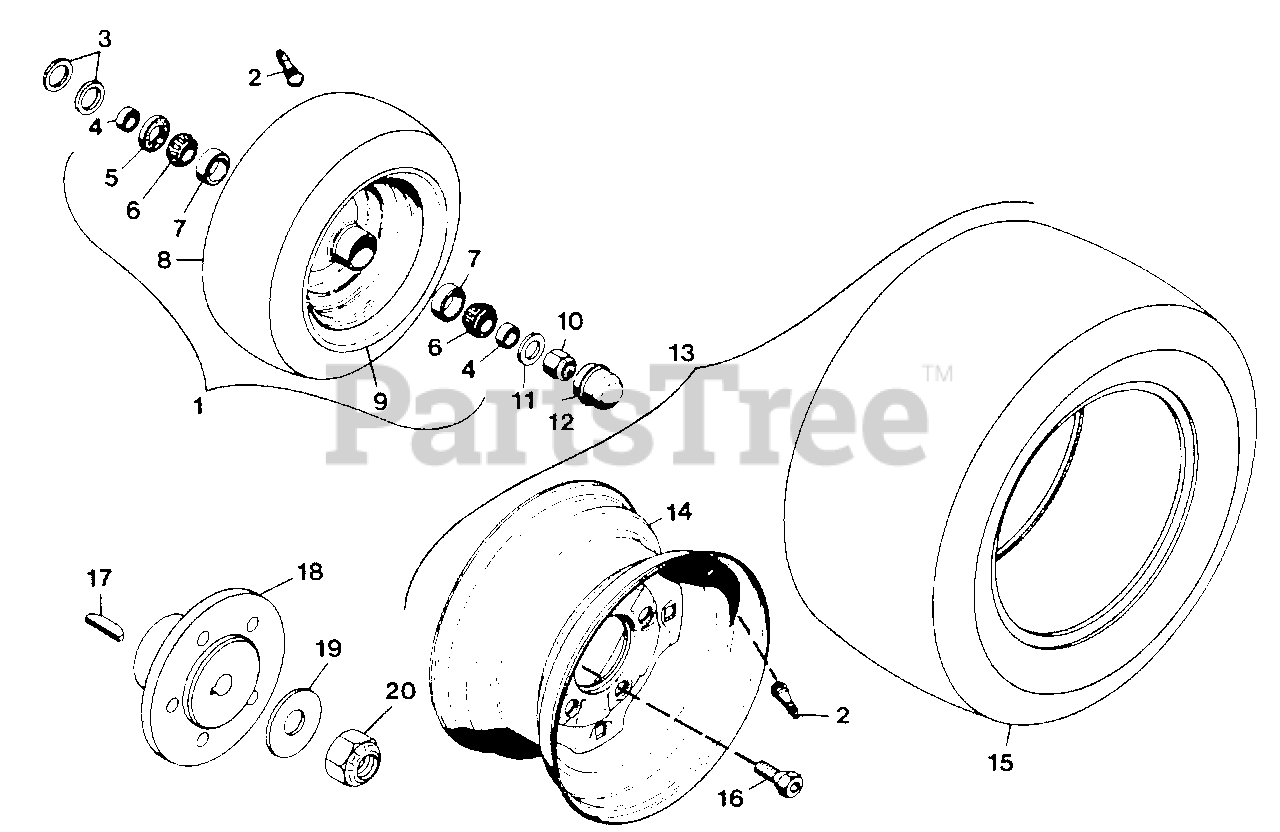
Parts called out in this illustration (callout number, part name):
1	ASSEMBLY, FRONT WHEEL 16X6.50-8
1	ASSEMBLY, FRONT WHEEL 16X7.50-8
2	ASSEMBLY, VALVE STEM
3	WASHER, FLAT .813X1.37X.100
4	SPACER
5	SEAL, OIL
6	BEARING, CONE LM 11949
7	BEARING, CUP LM 11910
8	TIRE, FRONT 16X6.50-8
8	TIRE, FRONT 16X7.50-8
9	RIM, FRONT WHEEL ASSEMBLY
10	NUT, LOCK 5/8-11
11	WASHER, FLAT .656X1.312X.095
12	CAP
13	ASSEMBLY, REAR WHEEL 23X8.50-12
13	ASSEMBLY, WHEEL R.H. 23X8.5-12 SGT
13	ASSEMBLY, WHEEL L.H. 23X8.5-12 SGT
13	ASSEMBLY, REAR WHEEL 23X10.50-12
14	RIM, WELDMENT
15	TIRE, REAR 23X8.50-12
15	TIRE, SUPER TERRA 23X8.50-12
15	TIRE, REAR 23X10.50-12
16	BOLT, HUB 7/16-20X.75(SPECIAL)
17	KEY, WOODRUFF .250X2.125 SOFT
18	HUB, TAPERED 4-WHEEL
19	WASHER, FLAT .813X2.0X.148
20	NUT, LOCK 3/4-10
